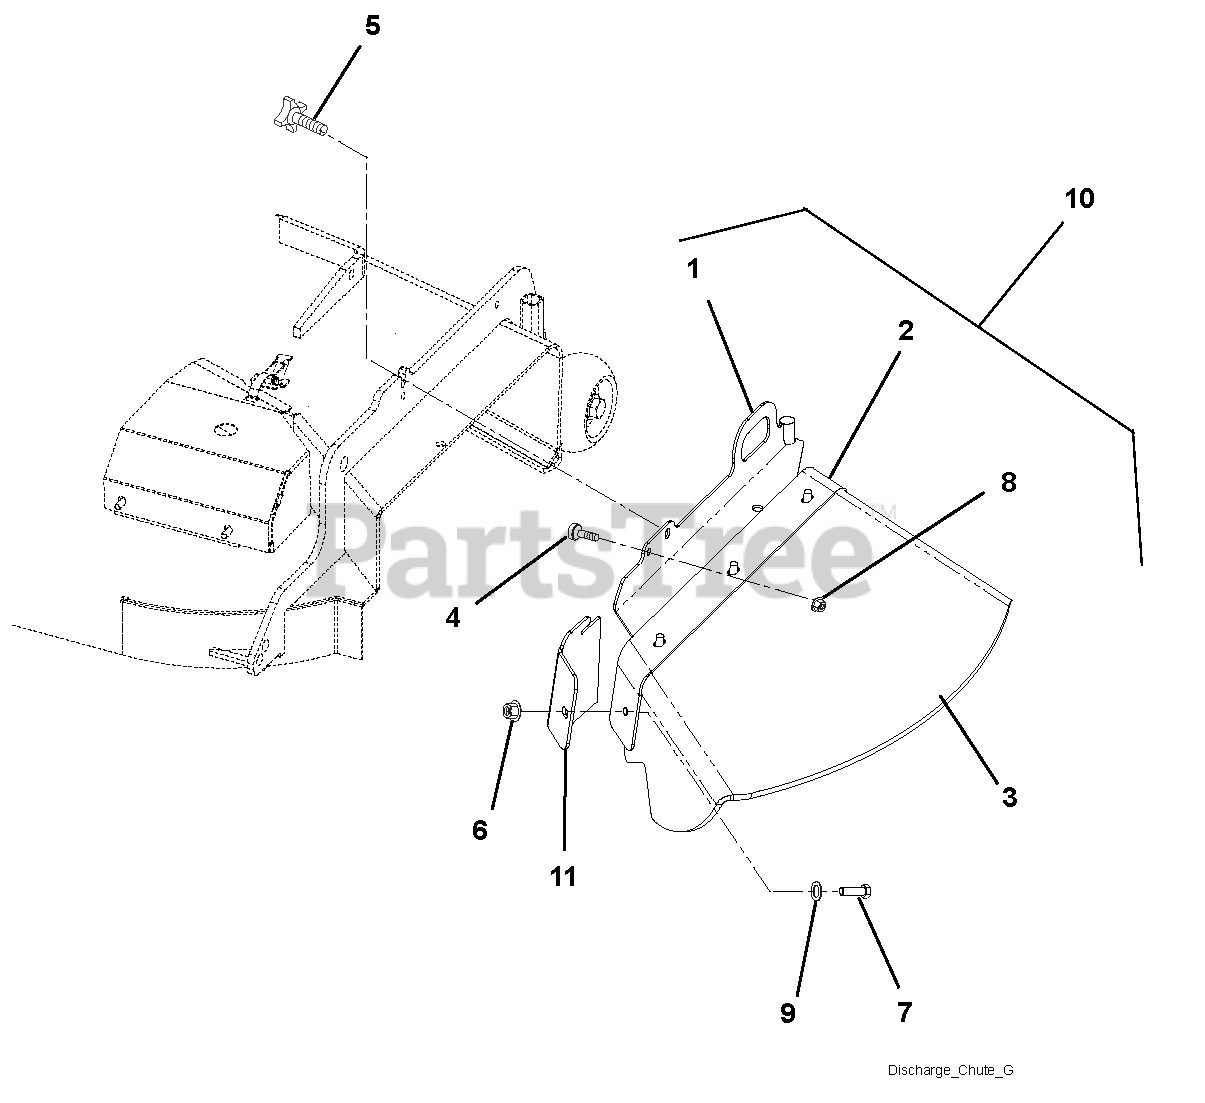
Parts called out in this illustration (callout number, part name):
1	WLDT, DISCH CHUTE MNT
2	PLATE, DISCHG SHIELD SUPPORT
3	SHIELD, RUBBER DISCHARGE
4	BUMPER, RUBBER
5	KNOB, 3/8 X 1.25 - 4 PRONG
6	LOCKNUT, 3/8-16 WHIZ Y
7	BOLT, 3/8-16X1.00 CRG 5 Y
8	LOCKNUT, 5/16-18 WHIZ Y
9	WASHER, .500 REG FLAT Y
10	ASSY, DISCHARGE-RUBBER GRAVELY
11	54" DISCHARGE COVER
